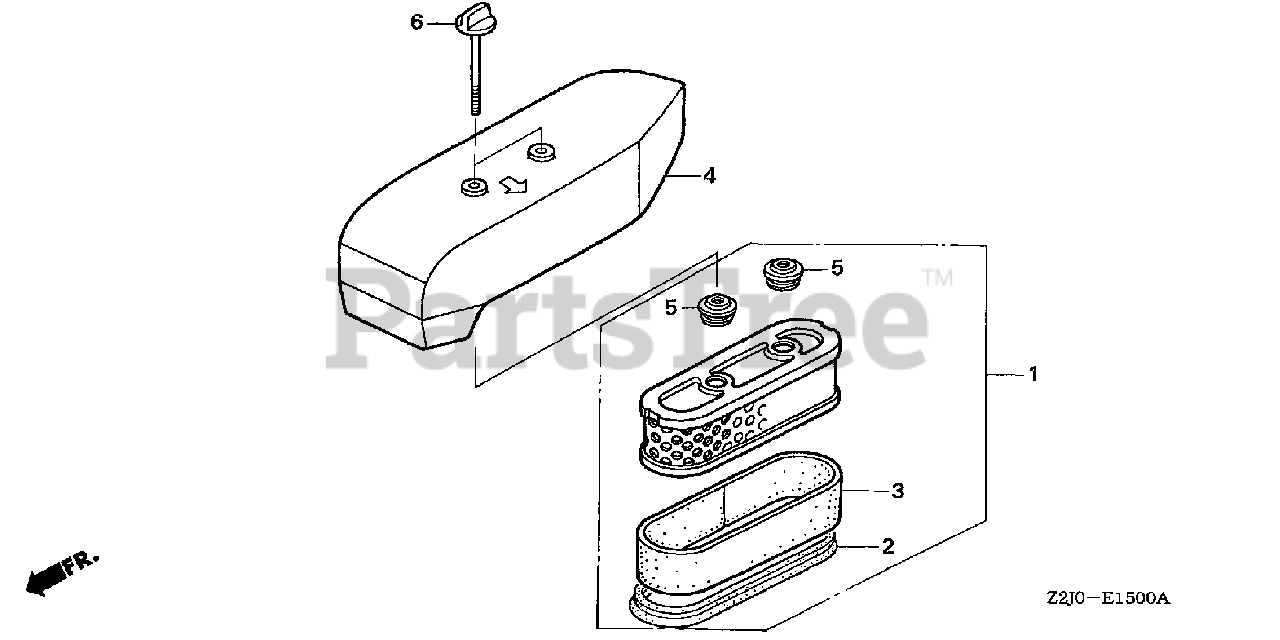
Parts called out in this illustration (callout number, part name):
1	ELEMENT, AIR CLEANER (TOYO)
2	GASKET, ELEMENT
3	FILTER (OUTER)
4	COVER, AIR CLEANER *NH1* (BLACK)
5	GROMMET, AIR CLEANER
6	BOLT, AIR CLEANER (6X73)
